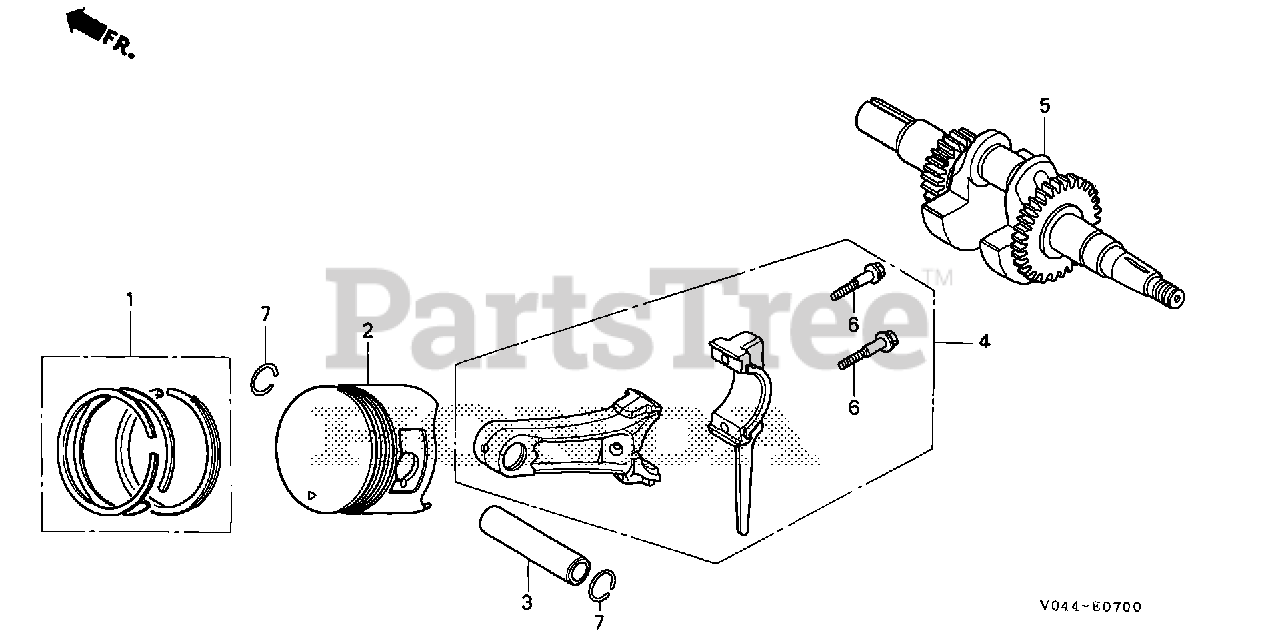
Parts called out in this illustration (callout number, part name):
1	RING SET, PISTON (STD) (TEIKOKU)
1	RING SET, PISTON (STD.) (NIPPON)
1	RING SET, PISTON (OS 0.25) Use from Engine SN 7603339.
1	RING SET, PISTON (0.25) (NIPPON) Use up to Engine SN 1314912.
1	RING SET, PISTON (OS 0.50) Use from Engine SN 7603339.
1	RING SET, PISTON (0.50) (NIPPON) Use up to Engine SN 1314912.
1	RING SET, PISTON (0.75) (TEIKOKU) Use up to Engine SN 1314912.
1	RING SET, PISTON (0.75) (NIPPON) Use up to Engine SN 1314912.
2	PISTON (STD)
2	PISTON (OS 0.25) Use from Engine SN 1645602.
2	PISTON (OS 0.50)
2	PISTON (0.75) Use from Engine SN 1645602.
3	PIN, PISTON
4	ROD ASSY., CONNECTING
4	ROD ASSY., CONNECTING (STD)
5	CRANKSHAFT (S-TYPE)
5	CRANKSHAFT
6	BOLT, CONNECTING ROD
7	CLIP, PISTON PIN (18MM)
